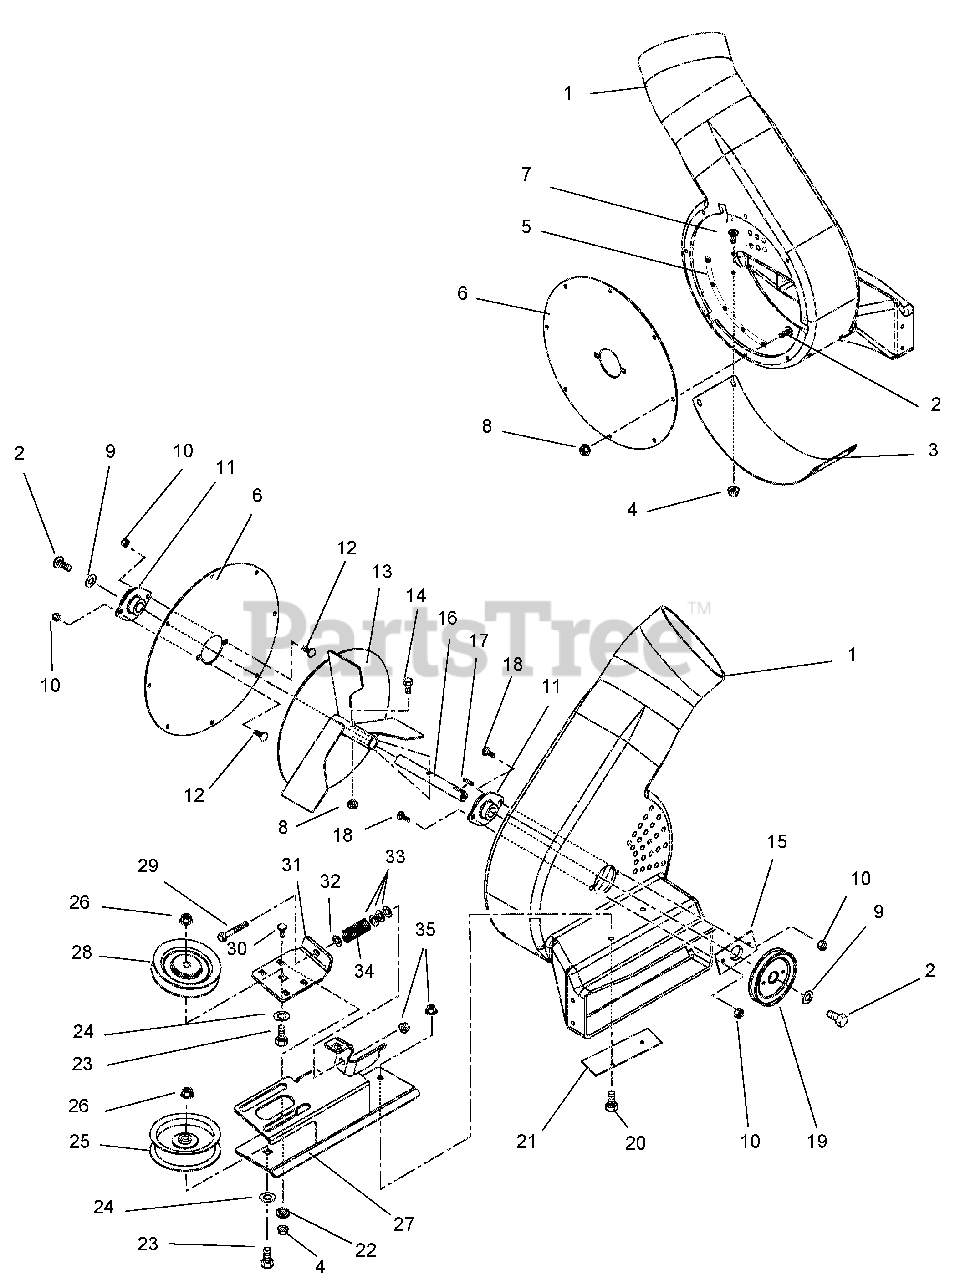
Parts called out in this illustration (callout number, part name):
1	Housing, Blower
2	Bolt, Hex .25-20 x .50 Epoxy
3	Plate, Skid
4	Nut, Locking-Top-Flange .25-20
5	Plate, Mounting Bolt Reinforcing
6	Plate, Bearing Mount
7	Screw, Machine .25-20 x .75
8	Nut, .25-20 Nyloc Flange
9	Washer, Flat-Steel .344 x 1.125 x .135
10	Nut, Locking-Nylon .312-18
11	Bearing, 2 Bolt Flange - .75 ID
12	Bolt, Round Head Square Neck .31-18 x .62
13	Weldment, Impeller, 3 Blade
14	Bolt, Hex .25-20 x 1.50 Grade 5
15	Plate, Washer Bearing
16	Shaft, Impeller
17	Key, Square .187 x .50 x .187 Hardened
18	Bolt, Round Head Square Neck .31-18 x .88 Grade 5
19	Sheave, Blower 4.25 Diameter
20	Bolt, Hex .31-18 x .875 Grade 5
21	Plate, Back
22	Bushing, Flange .265 x .437 x .250 x .750
23	Bolt, Hex .38-16 x 1.75 Grade 5
24	Washer, Flat-Steel .406 x .812 x .065
25	Idler Flanged 3.50
26	Nut, Locking-Top-Flange .38-16
27	Weldment, Idler Mount
28	V-Idler, 4.00 x .38
29	Bolt, Hex .31-18 x 4.00 Grade 5
30	Bolt, Round Head Square Neck .25-20 x .75 Grade 5
31	Bracket, Adjustable Idler
32	Nut, Push .312
33	Washer, Flat-Steel .406 x 1.00 x .188
34	Spring, Compression .092 x .77 x 3.13
35	Nut, Locking-Top-Flange .31-18
36	Blower, Service Assembly (includes items 1-35)
